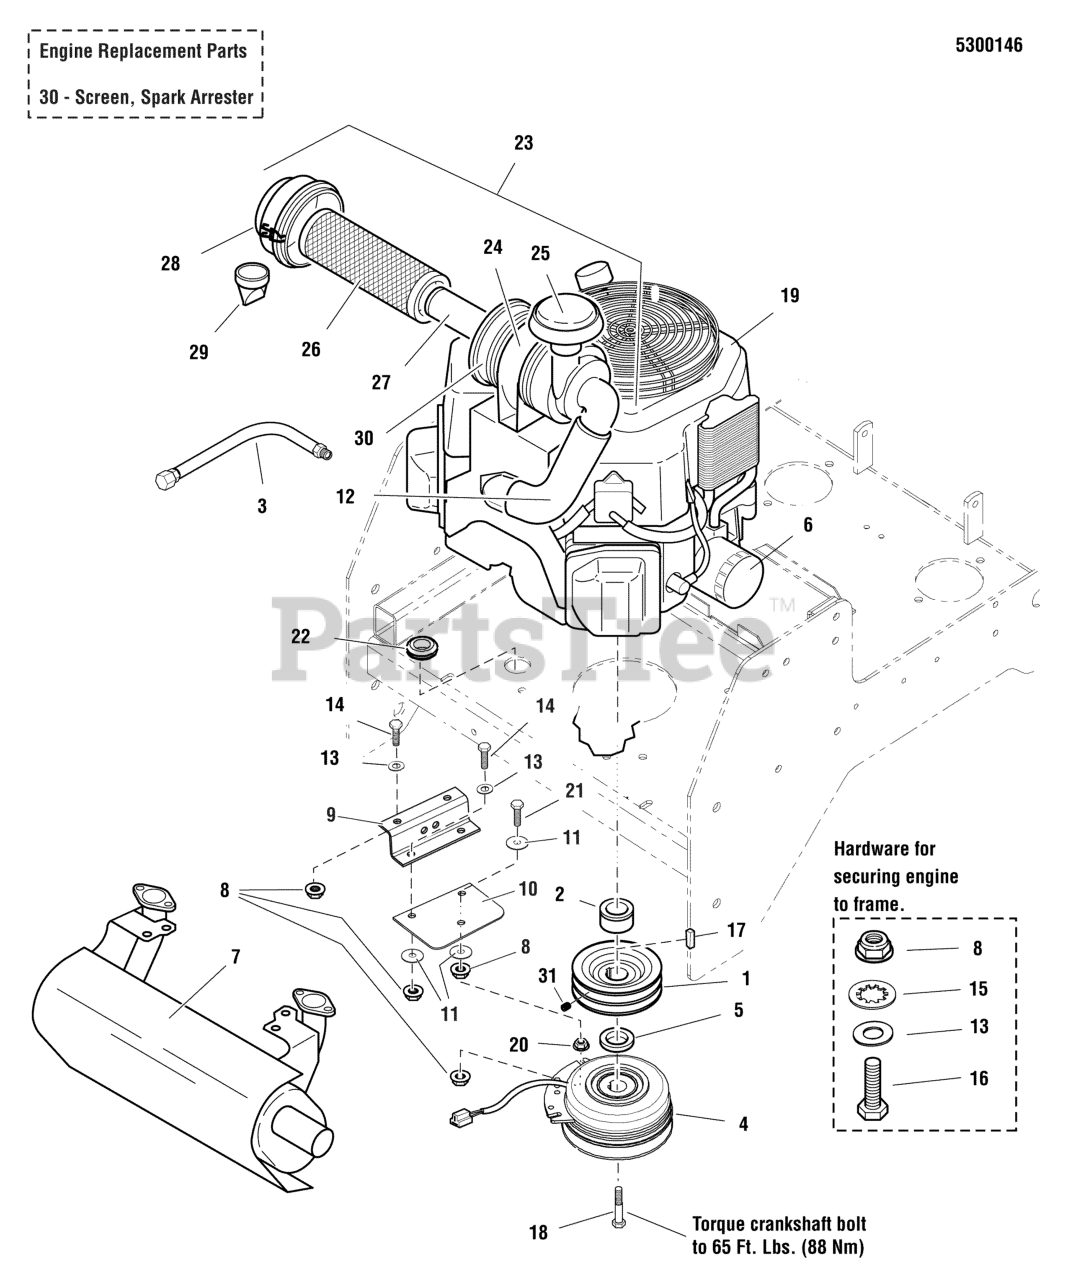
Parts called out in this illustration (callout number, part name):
1	PULLEY CRANKSHAFT (DOUBLE A)
2	SPACER, 1.13 X 1.75 X 1.03
3	HOSE, OIL DRAIN
4	* CLUTCH, 5218-134, WARNER
5	SPACER, 1.13 X 1.75 X .50
6	OIL FILTER (12 050 01)
7	MUFFLER, KOHLER 21 HP - 27 HP
8	NUT, 5/16-18 HEX NYLOCK FLANGE
9	ANCHOR, CLUTCH - BLK
10	CLUTCH ANCHOR PAD
11	WASHER, CLUTCH ANCHOR
12	INLET HOSE (25 326 53-S)
13	WASHER, 5/16" SAE
14	BOLT, 5/16-18 X 1" GD5 YZ
15	WASHER, 5/16" INT. TOOTH LOCK
16	BOLT, 5/16-18 X 1-3/4" GD5
17	KEY, 1/4 SQ X 1
18	BOLT, CRANKSHAFT 7/16 X 2 1/2
19	ENGINE, 27HP KOHLER, VERTICAL
20	NUT, 5/16-18 HEX SERRATED FLANGE (LARGE)
21	BOLT, 5/16-18 X 2-1/4 TFL, GD5 YZ
22	GROMMET, 7/8
23	KIT, 5.5" HD AIR CLEANER (24 743 22-S)
24	HOUSING MOUNT BRACKET (25 126 02-S)
25	RAIN COVER
26	PRIMARY PAPER ELEMENT
27	SECONDARY ELEMENT
28	END CAP (25 096 06-S)
29	DUST VALVE (24 462 07-S)
31	SET SCREW, 5/16-18 X 3/8, KNURL, W/PATCH
